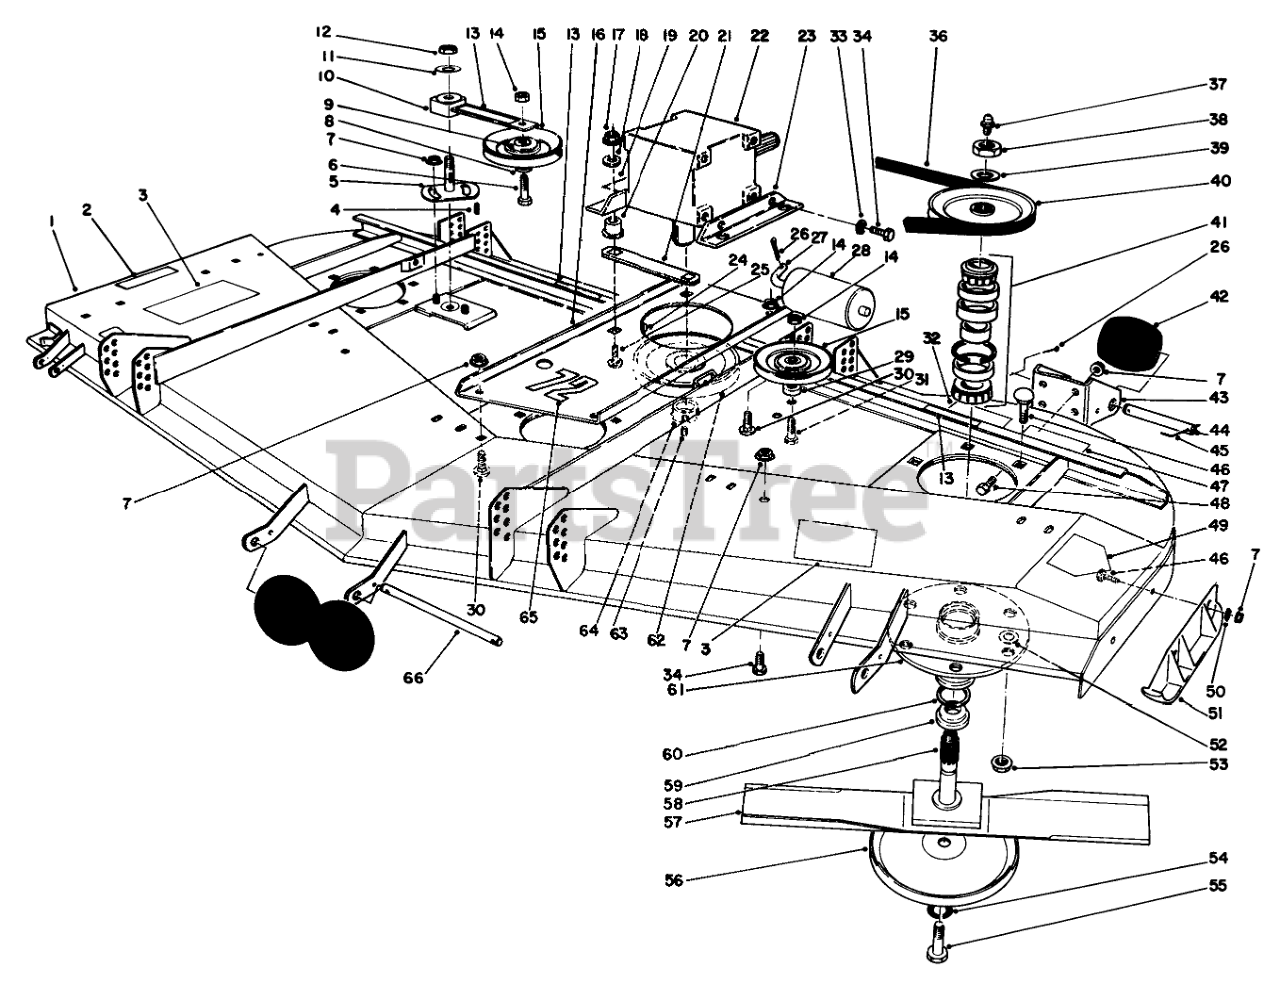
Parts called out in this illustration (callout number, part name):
1	Housing
2	DECAL-DANGER
3	DECAL-DANGER, THROWN OBJECT
4	KEY-SQUARE
5	PLATE-IDLER
6	SCREW-HH
7	NUT-HHF, WHIZ
8	BUSHING-PULLEY
9	WASHER-FLAT
10	IDLER ARM ASM
11	WASHER-FLAT
12	NUT-LOCK, NI
13	DECAL-DANGER
14	NUT-HEX
15	PULLEY-IDLER
16	Base-Gear Box
17	NUT-LOCK, SIDE
18	WASHER
19	DECAL-OIL
20	MOUNT
21	Cover-Gear Box
22	Gearbox
23	Bracket-Gearbox
24	KEY-WOODRUFF
25	SCREW-CARR
26	PIN-COTTER
27	SHAFT-ROLLER, REAR
28	ROLLER-DECK
29	SPACER
30	SCREW-CARR
31	SCREW-HH
32	DECAL-TORQUE
33	WASHER-LOCK
34	SCREW-HH
36	V-BELT (72)
37	FITTING-GREASE
38	NUT-HEX
39	WASHER
40	PULLEY & HUB ASM, WELDED
41	BEARING ASM
42	ROLLER
43	Bracket-Roller
44	SHAFT-ROLLER
45	PIN-SPECIAL
46	SCREW-CARR
47	DECAL - WARNING
48	SCREW-HH
49	DECAL-DANGER
50	LOCKWASHER-PYRAMID
51	Skid
52	WASHER-FLAT
53	NUT-HF
54	WASHER
55	SCREW-BLADE
56	CUP-SCALP, ANTI
57	Blade
58	SHAFT
59	SPACER
60	SEAL-OIL
61	HOUSING-SPINDLE
62	PULLEY
63	SCREW-SET, HSH
64	Bushing-Taper Lock (Incl. Ref. #63)
65	DECAL
66	SHAFT-ROLLER
